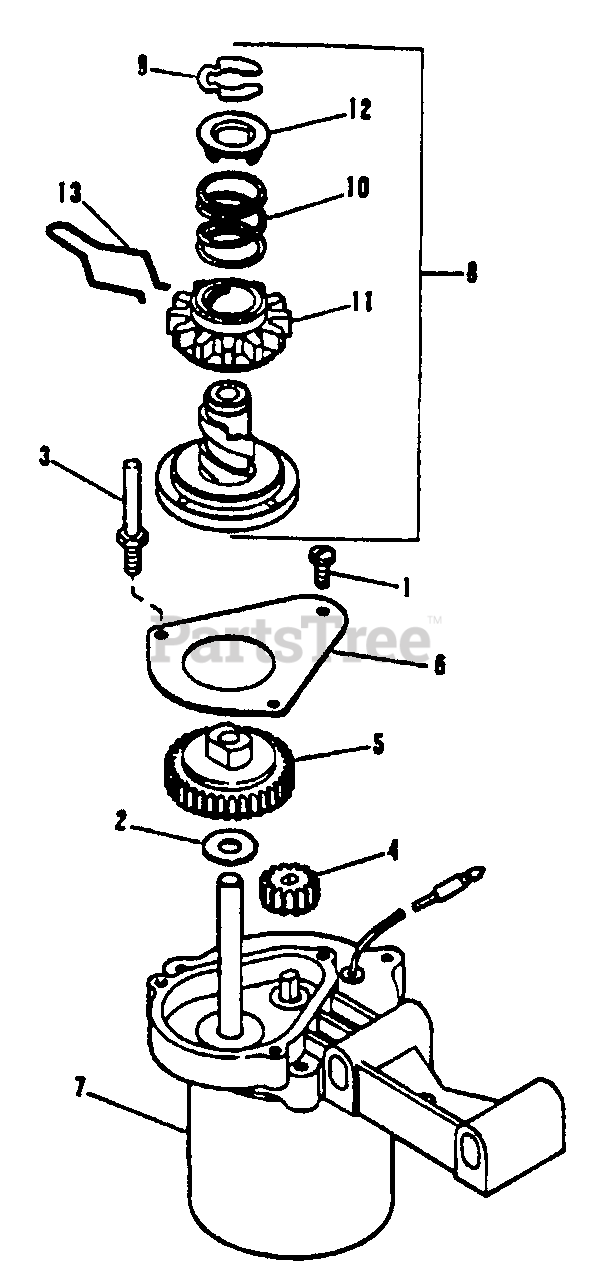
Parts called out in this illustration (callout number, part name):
1	Screw
2	Washer-Thrust
3	Stud-Drag Spring
4	Pinion
5	Gear-Driven
6	Plate Gear Cover
7	Motor Housing & Pin Assy
8	Pinion, Spring & Clutch Assy (Inc. 9-13)
9	Retaining Ring
10	Spring-Pinion
11	Pinion
12	Stop Washer
13	Spring-Drag
